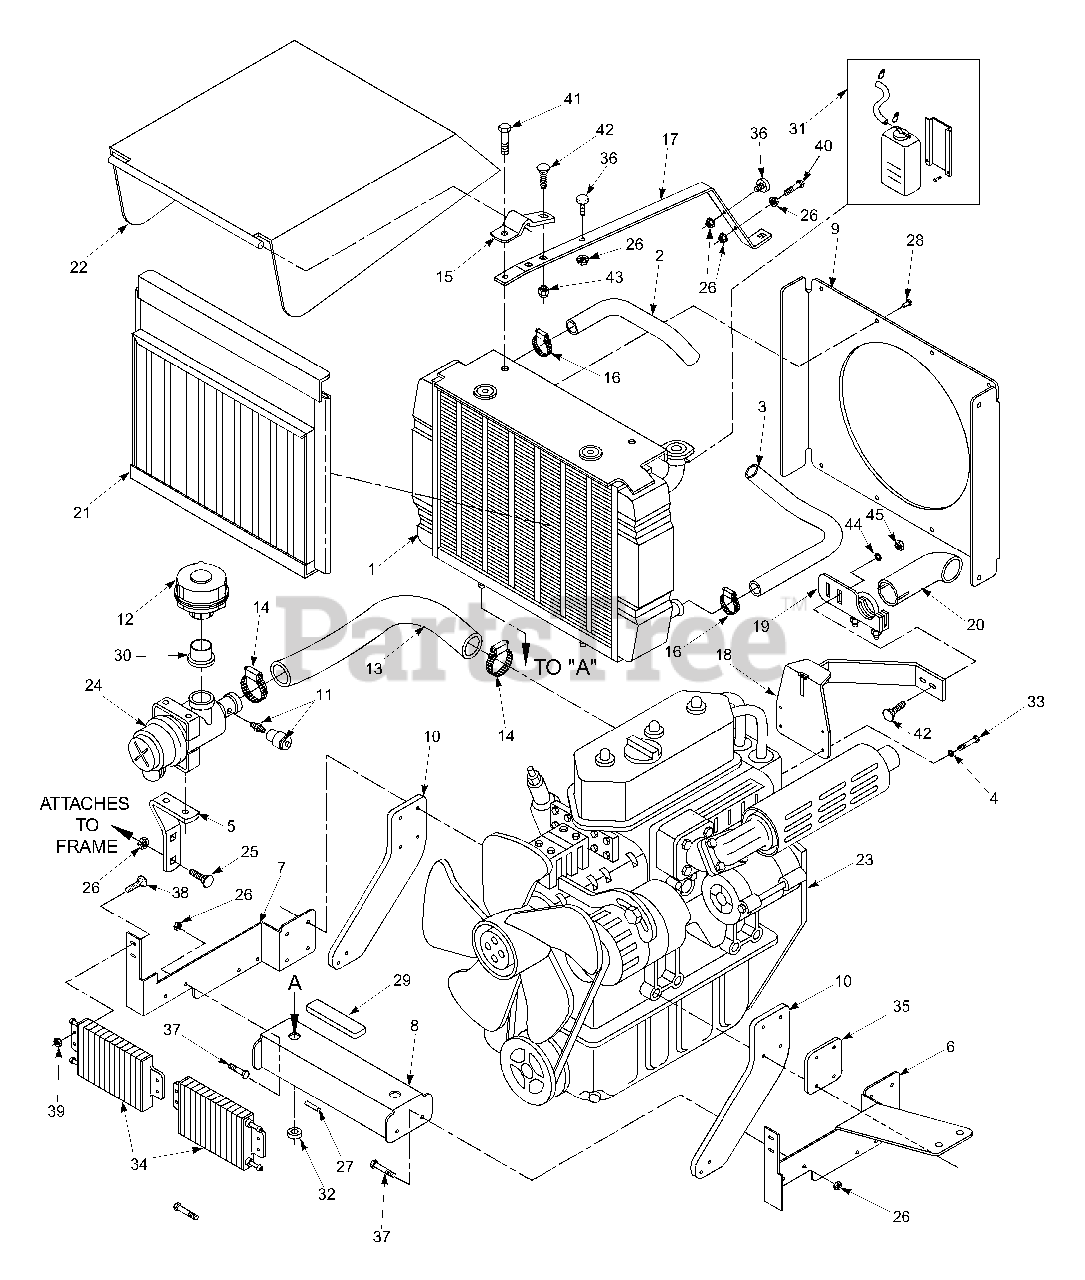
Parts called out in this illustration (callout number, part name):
1	Radiator
2	Hose, Upper Radiator
3	Hose, Lower Radiator
4	Lockwasher, 5/16 (.317 x .586 x .078) Helical Spring
5	Bracket, Air Cleaner
6	Bracket, Engine Mounting LH
7	Bracket, Engine Mounting RH
8	Bracket, Radiator Mounting
9	Shroud, Radiator
10	Plate, Engine Mounting
11	Indicator, Air Cleaner
12	Pre-Cleaner, Engine Air
13	Hose, Air Intake
14	Clamp, Hose (2.25" Dia.)
15	Hinge, Hood
16	Clamp, Hose (1.50" Dia.)
17	Bracket, Hood Support
18	Bracket, Exhaust Support
19	Clamp Weldment, Muffler (Clamp and Weldment)
20	Elbow, Exhaust
21	Screen, Debris
23	Engine, Briggs & Stratton 31 HP
24	Air Cleaner Assembly w/ Mounting Band
25	Bolt, Carr. 5/16-18 x .75"
26	Nut, Serr. Flng 5/16-18
27	Pin, Rue Cotter 1/2" dia.
28	Rivet, Pop 1/8 x .294"
29	Pad, Radiator
30	Adaptor, Pre-Cleaner
31	Coolant Tank Assembly w/Hose
32	Spacer, Radiator
33	Bolt, Hex Head M8 x 20MM LG
34	Cooler, Oil
35	Engine Spacer
36	Bumper, Rubber
37	Bolt, Hex Head 5/16-18 x .75"
38	Bolt, Carrage 1/4-20 x .50"
39	Nut, 1/4-20 Serrated Flange
40	Bolt, Hex Head 5/16-18 x 1.50"
41	Bolt, Hex Head 5/16-18 x .75 Serrated Flange
42	Bolt, Carrage 5/16-18 x 1.0"
43	Nut, 5/16-18 Elastic Stop
44	Flatwasher, 5/16 (.375 x .875 x .083)
45	Nut, 5/16-18 Elastic Stop
